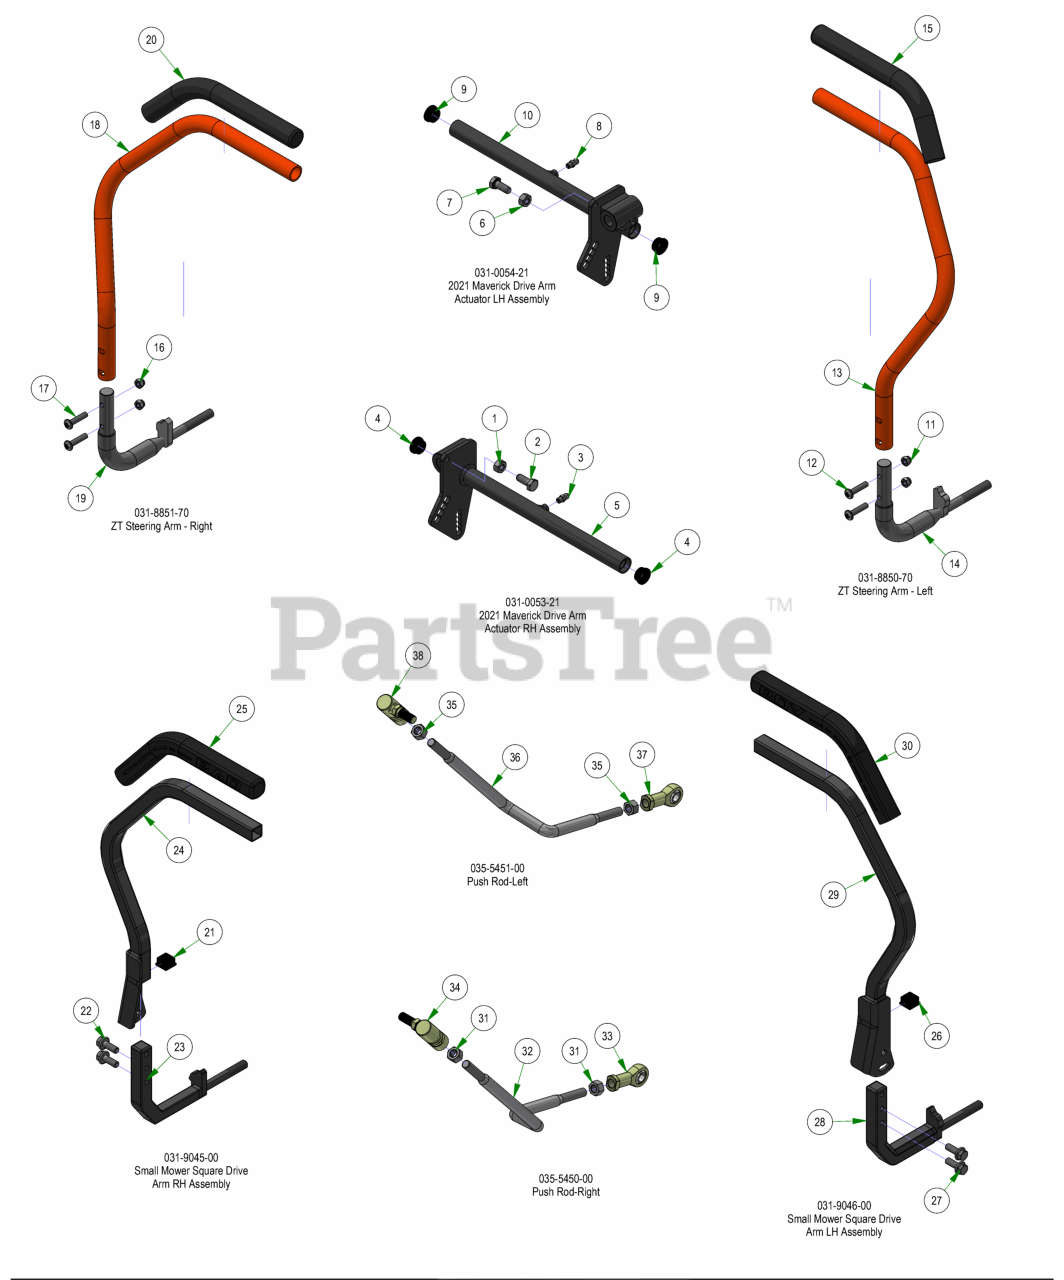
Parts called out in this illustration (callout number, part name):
1	5/16-18 HEX NUT ZINC
2	5/16-18 X 3/4 HEX CAP SCREW (GR.5) ZINC
3	1/4 DRIVE-TYPE STRAIGHT GREASE FITTING ZINC YELLOW)
4	2019 Drive Arm Bushing
5	2021 Drive Actuator RH Weldment
6	5/16-18 HEX NUT ZINC
7	5/16-18 X 3/4 HEX CAP SCREW (GR.5) ZINC
8	1/4 DRIVE-TYPE STRAIGHT GREASE FITTING ZINC YELLOW)
9	2019 Drive Arm Bushing
10	2021 Drive Actuator LH Weldment
11	5/16-18 NYL INS L/N ZC
12	5/16-18 x 1 3/8" Button Head Torx Drive Bolt
13	ZT Direction Steering Arm (Left)
14	Steering Arm Elbow (Left)
15	Rubber Grip
16	5/16-18 NYL INS L/N ZC
17	5/16-18 x 1 3/8" Button Head Torx Drive Bolt
18	ZT Direction Steering Arm (Right)
19	Steering Arm Elbow (Right)
20	Rubber Grip
21	9565K16_Polyethylene Square Plug
22	92323A554_Grade 5 Steel Serrated-Flange Hex Head Screw
23	Small Mower Square Drive Arm Lower RH Weldment
24	Small Mower Square Drive Arm RH Weldment
25	Grip for 031-9045-00 / 031-9046-00
26	9565K16_Polyethylene Square Plug
27	92323A554_Grade 5 Steel Serrated-Flange Hex Head Screw
28	Small Mower Square Drive Arm Lower LH Weldment
29	Small Mower Square Drive Arm LH Weldment
30	Grip for 031-9045-00 / 031-9046-00
31	3/8" Fine Threaded Jam Nut
32	Push Rod - Right (Rod Only)
33	Spherical Rod End - Outlaw
34	Quick Release Ball Joint
35	3/8" Fine Threaded Jam Nut
36	Push Rod LH (Rod Only)
37	Spherical Rod End - Outlaw
38	Quick Release Ball Joint
